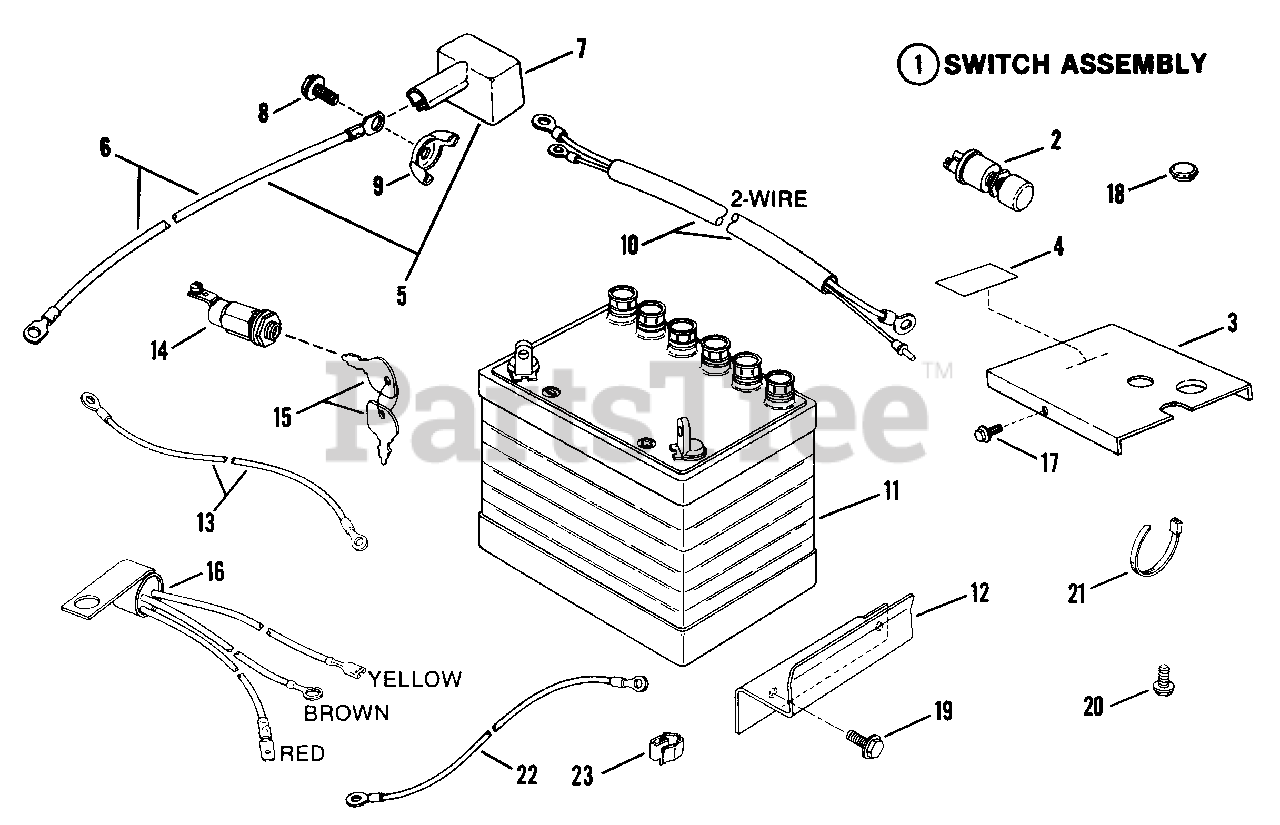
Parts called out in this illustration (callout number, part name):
1	SWITCH ASS'Y.
2	SWITCH, Pushbutton Start
3	PANEL, Switch (NLA, use 38240 and drill .641" switch hole)
4	DECAL, Pushbutton Electric Start
5	ASSEMBLY, Wire & Cover
6	CABLE, Positive Red
7	COVER, Battery Cable
8	CAPSCREW, Hex Head 5/16-18x3/4
9	WING-NUT, 5/16-18
10	HARNESS, Starter Wiring
11	KIT, 12V Dry Charge Battery
12	CLAMP, Battery Retaining
13	WIRE, Ground
14	SWITCH, Ignition
15	KEY, Switch (Pair)
16	INTERLOCK
17	SCREW, 1/4-28x5/8" Self-Tapping
19	SCREW, 5/16Cx5/8" Self-Tapping
20	CAPSCREW, 1/4-20x1/2" Self-Tapping, Hex Head
21	CABLE-TIE
22	CABLE, Negative
23	CLIP, Hose
